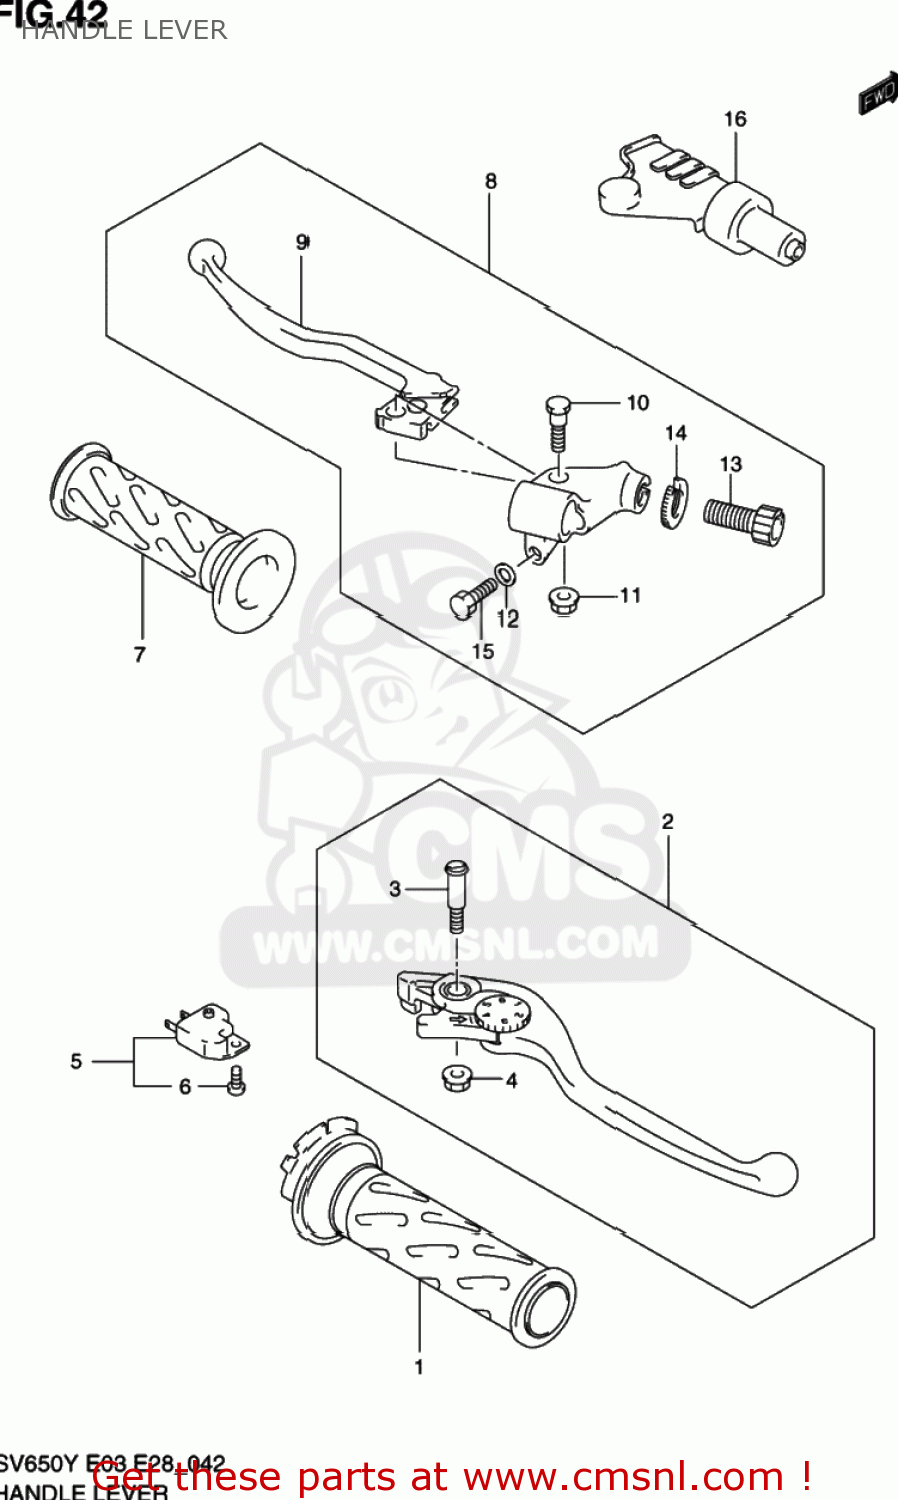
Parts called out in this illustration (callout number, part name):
1	GRIP,THROTTLE
2	LEVER ASSY,BRAKE
3	BOLT,LEVER PIVOT
4	NUT
5	SWITCH ASSEMBLY,STOP
6	SCREW
7	GRIP,LEFT
8	LEVER ASSY,CLUTCH
9	LEVER,CLUTCH
10	BOLT,LEVER SET
11	NUT
12	WASHER
13	ADJUSTER,CABLE
14	NUT,CABLE ADJUSTER
15	BOLT
16	COVER,CLUTCH LEVER
